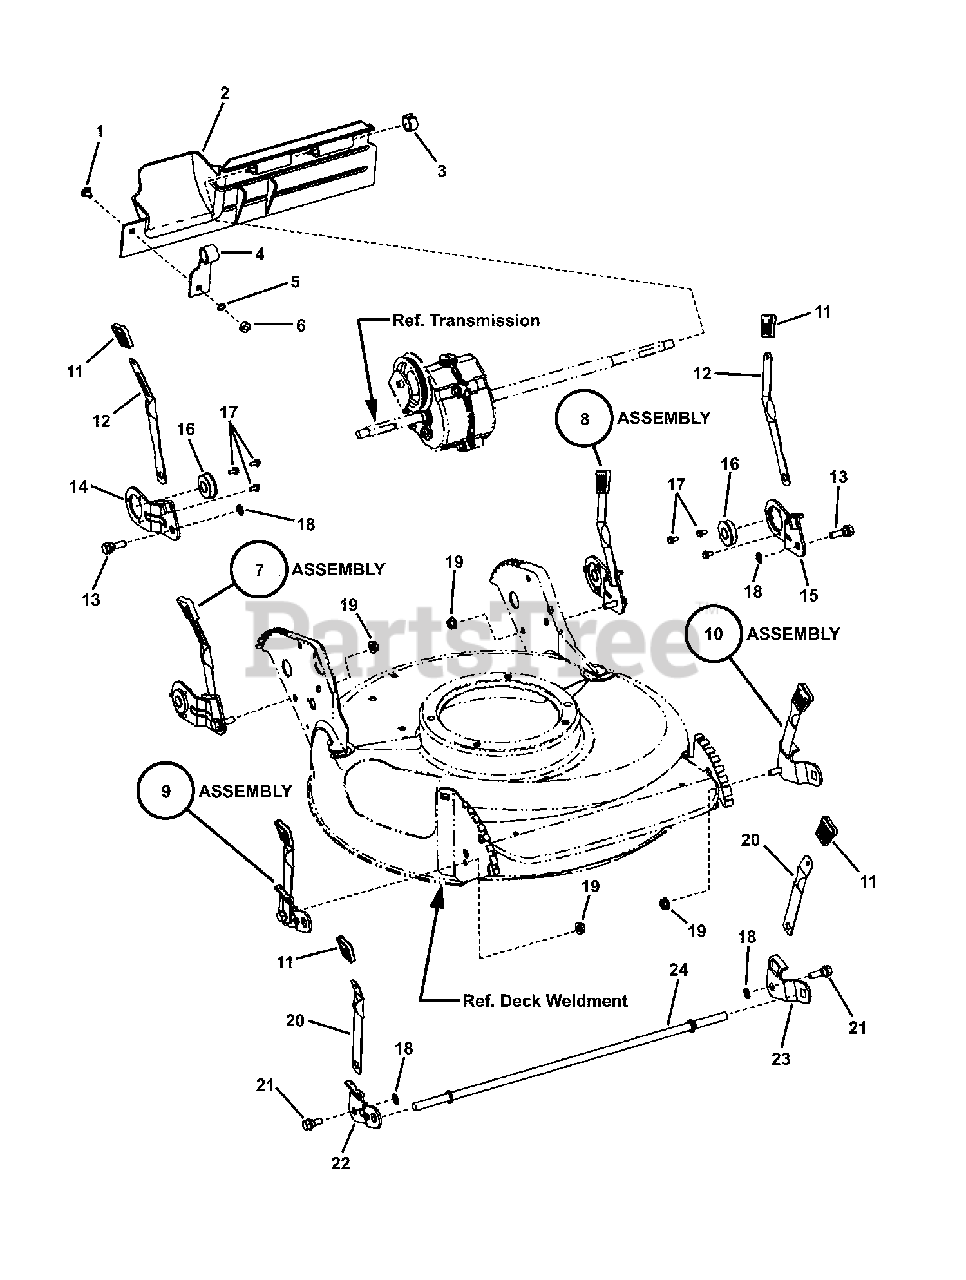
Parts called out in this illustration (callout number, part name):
1	BOLT, 1/4-20 x 1/2" Short Neck Carriage GR 5
2	FOOT GUARD, Rear
3	RING, Split (Black)
4	SUPPORT, Foot Guard
5	WASHER, 1/4" Internal Tooth Lock
6	NUT, 1/4-20 Hex, GR 5 or B
7	ASSY, Wheel Arm, Right Rear Long
8	ASSY, Wheel Arm Left Rear Long
9	ASSEMBLY, Wheel Arm, Front Right
10	ASSEMBLY, Wheel Arm, Front Left
11	GRIP, Height Latch
12	LATCH, Height Adjusting (long)
13	BOLT, 5/16-18 x 1" Hex Washer Face Shoulder
14	ARM, Wheel, Right Rear
15	ARM, Wheel, Left Rear
16	BEARING, 9/16" I.D.
17	SCREW, #10-32 x 3/8" Hex washer Self-Tap
18	RETAINER, 5/16" Bolt
19	NUT, 5/16-18 Hex Flange Lock, GR 5
20	LATCH, Height
21	BOLT, 5/16-18 x 3/4" Hex Washer Face Shoulder
22	WHEEL ARM, R.H. Front (Round Hole)
23	WHEEL ARM, L.H. Front (Square Hole)
24	AXLE, 21" (7/16-20 thread- both ends, 20.44" long)
